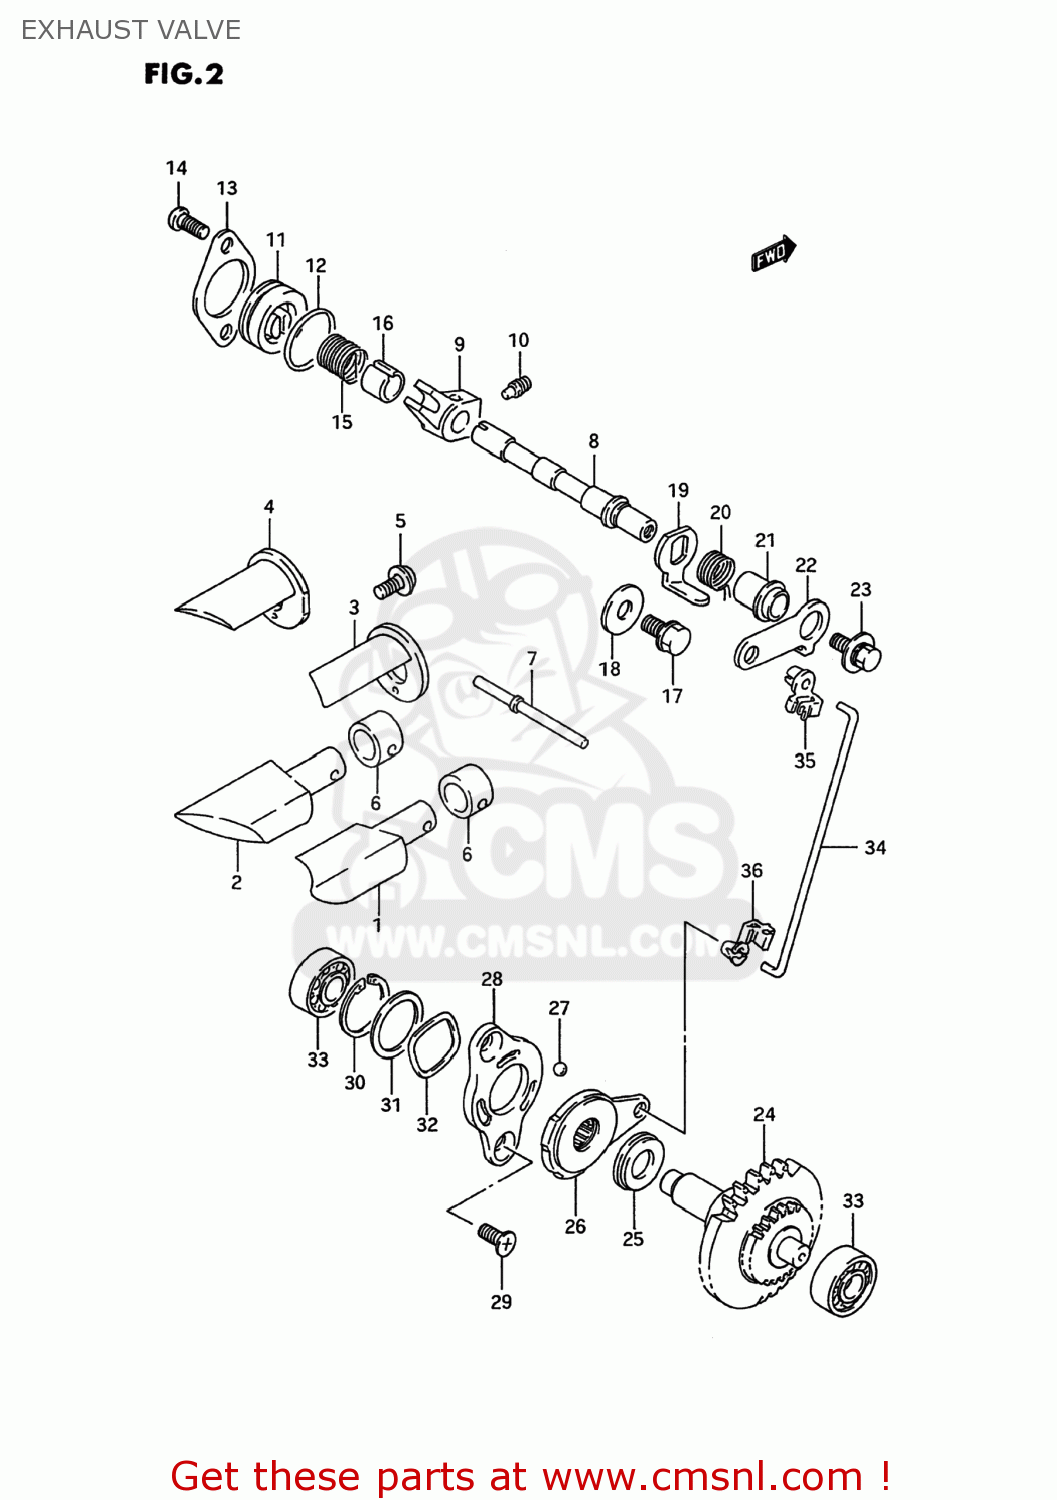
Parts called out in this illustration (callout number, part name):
1	VALVE,EXHAUST,R
2	VALVE,EXHAUST,L
3	GUIDE,EXHAUST VALVE,R
4	GUIDE,EXHAUST VALVE,L
5	SCREW
6	SPACER,EXHAUST VALVE
7	PIN,EXHAUST VALVE
8	SHAFT,EXHAUST VALVE
9	ARM,EXHAUST VALVE SHAFT
10	SCREW(6X10)
11	CAP,EXHAUST VALVE
12	O RING(D:1.9,ID:22.6)
13	RETAINER,EXHAUST VALVE
14	BOLT
15	SPRING
16	SPACER,EXHAUST VALVE SPRING
17	BOLT
18	WASHER
19	LEVER,EXHAUST VALVE NO
20	SPRING
21	SPACER,EXHAUST VALVE
22	LEVER,EXHAUST VALVE NO.1
23	BOLT(5X12)
24	GOVERNOR ASSY,EXHAUST VALVE
25	BEARING(10X22X2.8)
26	ACTUATOR,EXHAUST VALVE
27	BALL
28	STARTER,EXHAUST VALVE ACTUATOR
29	SCREW(5X10)
30	CIRCLIP
31	SHIM(19.1X25X0.3)
32	WASHER
33	BEARING(8X22X7)
34	ROD,EXHAUST VALVE
35	BUSH,EXHAUST VALVE ROD NO.1
36	BUSH,EXHAUST VALVE ROD NO.2
